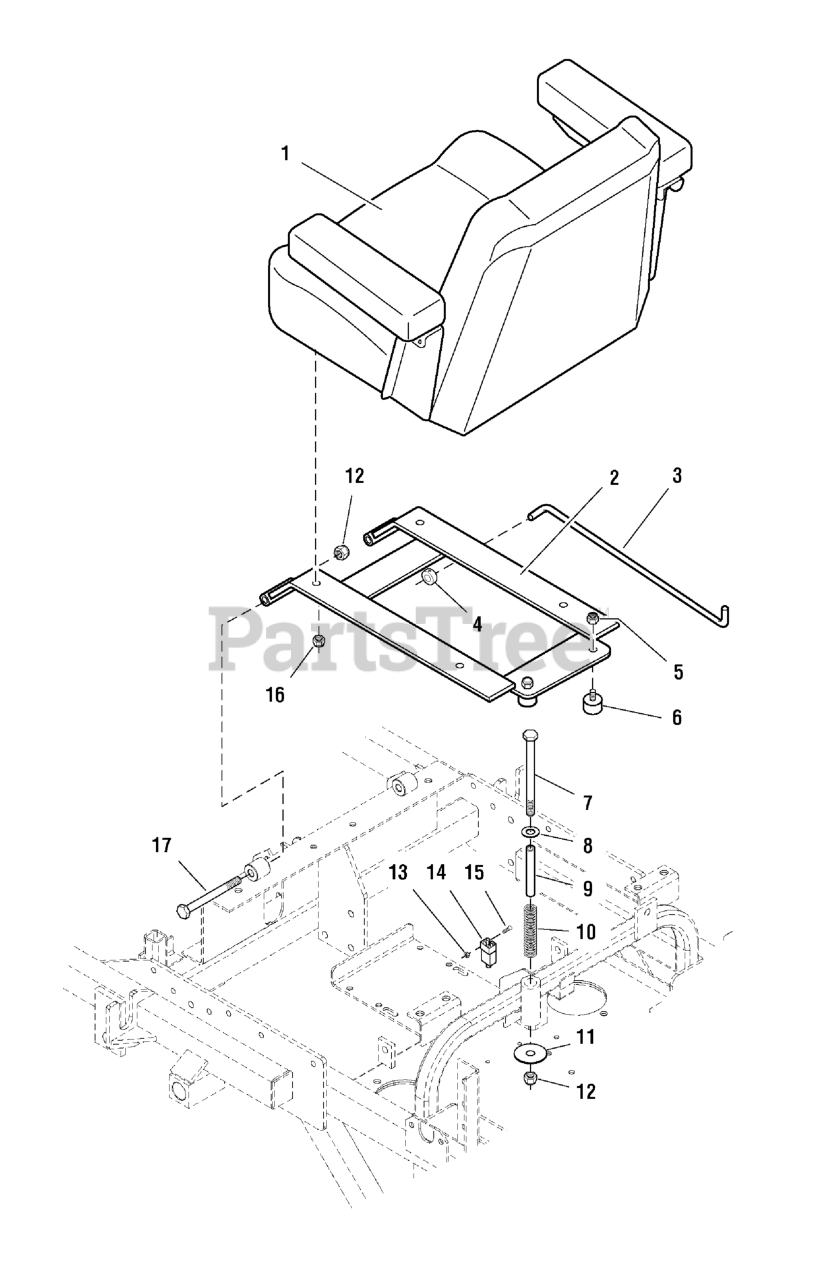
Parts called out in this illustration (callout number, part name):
1	SEAT, GRAY, NO LOGO, CMPT
1	SEAT BOTTOM (EVC 907)
1	CUSHION, Back, Gray
1	ARM REST, Black
1	SEAT ADJUSTER RAILS (set of 2)
2	WELD, SEAT MOUNT
3	SEAT STOP ROD
4	COLLAR, 5/16" Set
5	NUT, 1/4-20 HEX NYLON LOCK
6	RUBBER BUMPER
7	BOLT, 3/8-16 X 6" GD5 CZ
8	WASHER, 3/8 SAE
9	SPACER, .38 x .50 x 5.06
10	SPRING, Compression
11	WASHER, 3/8 x 2
12	NUT, 3/8-16 HEX NYLON LOCK
13	NUT, #10-24 Hex
14	SWITCH (see electrical group)
15	SCREW, #10-24 X 1 RS, CZ
16	NUT, 5/16-18 Hex Nylon Lock
17	BOLT, 3/8-16 X 4" GD5 CZ
18	SPRING, EXTENSION, SEAT ADJUSTMENT (YEL OR BLK)
